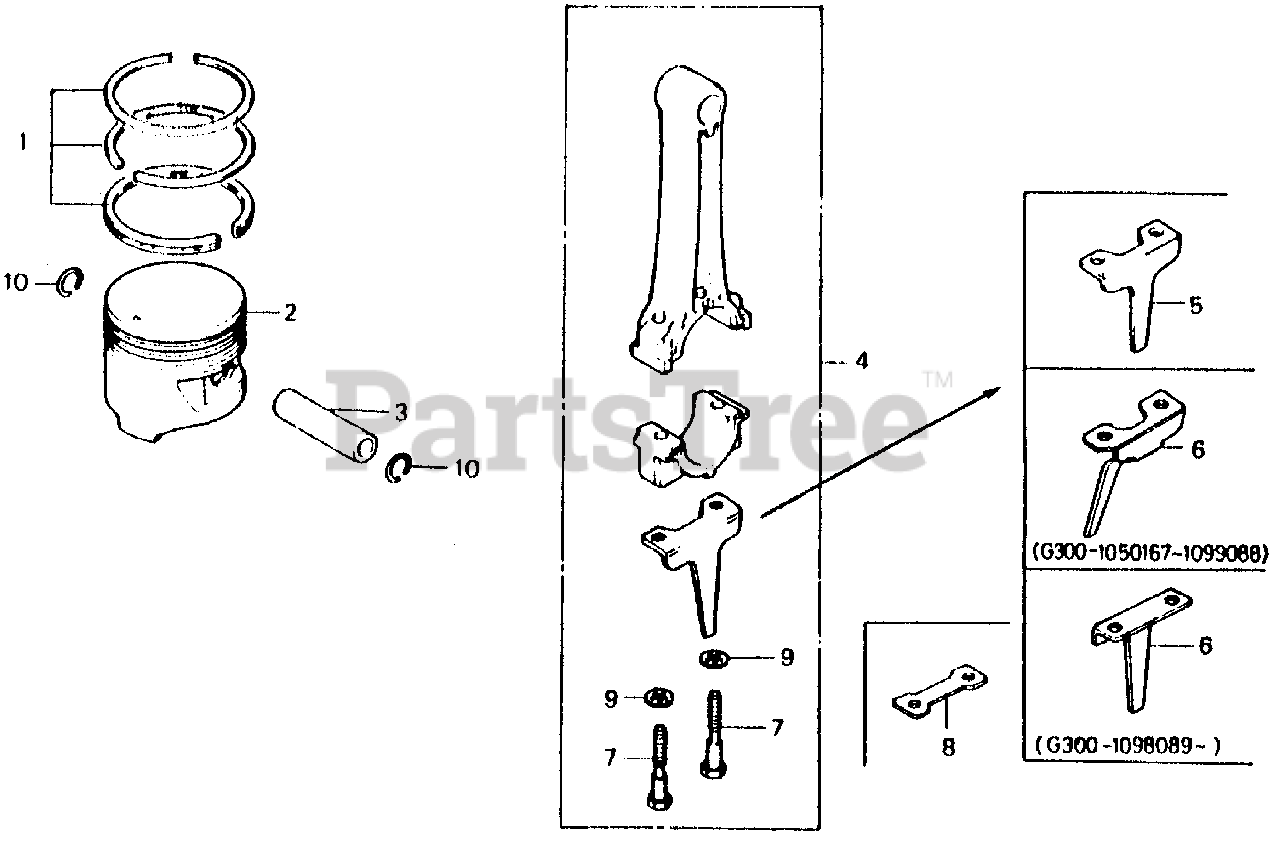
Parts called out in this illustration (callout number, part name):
1	RING SET, PISTON
1	RING SET, PISTON (OS 0.25)
1	RING SET, PISTON (OS 0.25) Use up to Engine SN 1061637.
1	RING SET, PISTON (OS 0.50)
1	RING SET, PISTON (OS 0.50) Use up to Engine SN 1061637.
1	RING SET, PISTON (0.75)
1	RING SET, PISTON (0.75) Use up to Engine SN 1061637.
2	PISTON (STD)
2	PISTON (OS 0.25)
2	PISTON (OS 0.50)
2	PISTON (0.75)
3	PIN, PISTON
4	ROD ASSY., CONNECTING
4	ROD ASSY., CONNECTING (US) Use up to Engine SN 1050166.
4	ROD ASSY., CONNECTING (US) Use from Engine SN 1050167.
5	DIPPER, CONNECTING ROD
6	DIPPER, CONNECTING ROD
7	BOLT, CONNECTING ROD (7MM)
7	BOLT, CONNECTING ROD (8MM) (NOT AVAILABLE)
8	WASHER, LOCK (7MM)
9	WASHER, LOCK (7MM)
10	CLIP, PISTON PIN (16MM)
